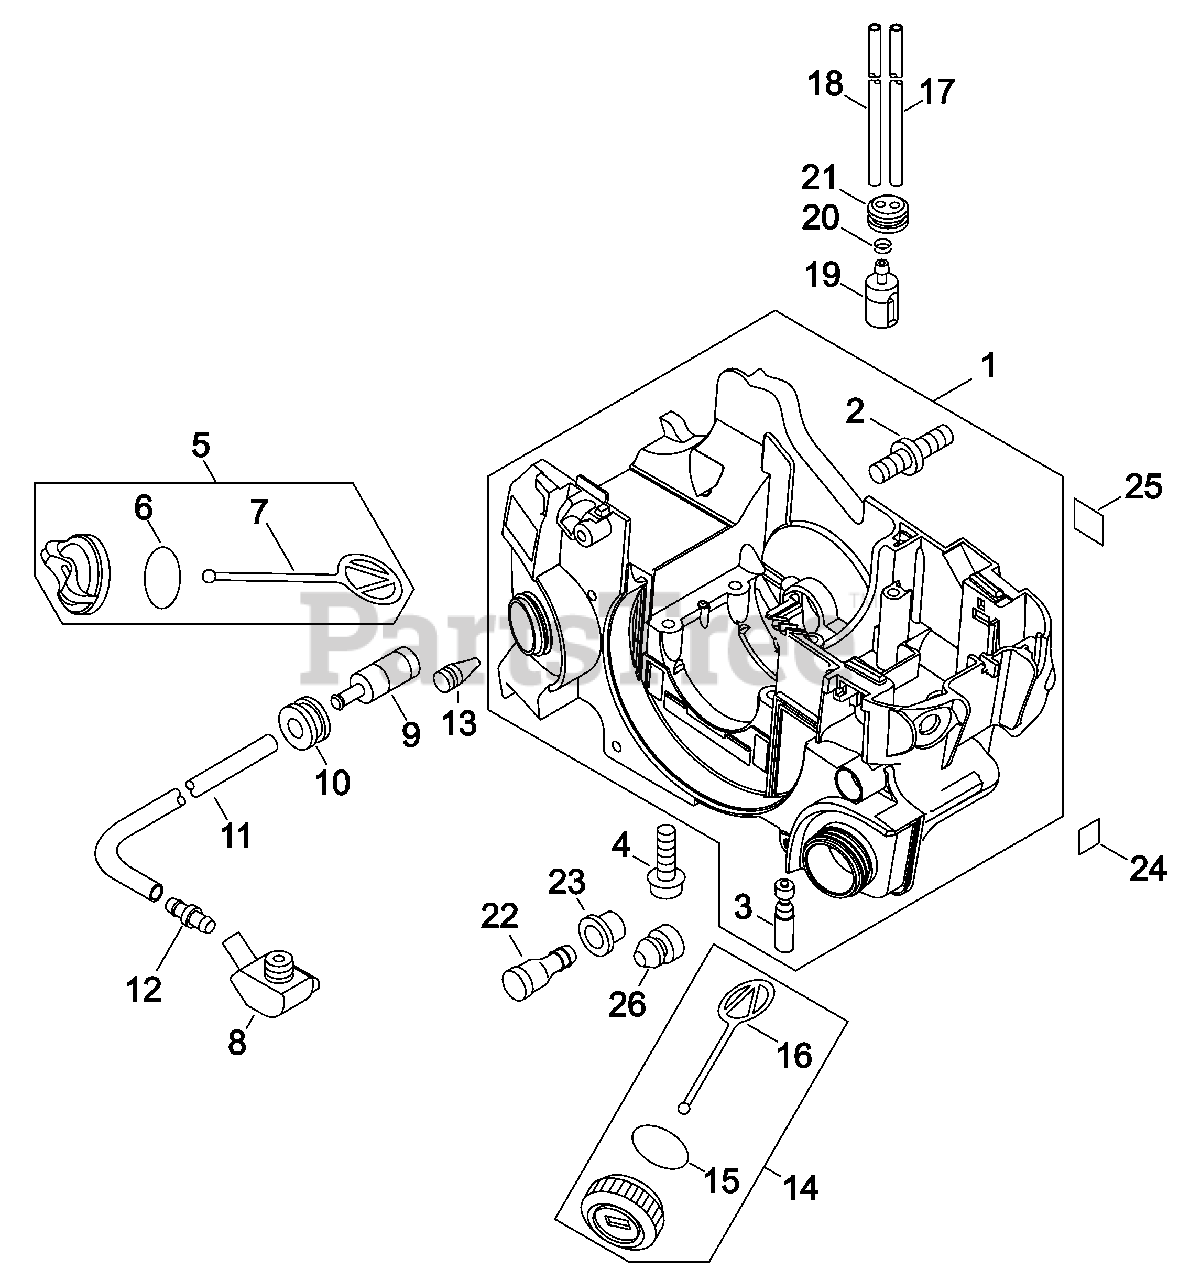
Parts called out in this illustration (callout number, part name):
1	HOUSING ASSY, ENGINE
2	BOLT, STUD 8
3	AUTO-OILER ASSY
4	BOLT, TORX 5×30
5	CAP ASSY - BLACK
6	O-RING 18
7	CONNECTOR, CAP L= 60 MM
8	GROMMET, OIL
9	FILTER, OIL
10	GROMMET
11	PIPE 3×6×185 MM BLACK
12	CONNECTOR, PIPE
13	VENT ASSY
14	CAP ASSY, FUEL
15	O-RING 22
16	CONNECTOR, CAP L= 60 MM
17	PIPE, FUEL 2.4×5×80 BLACK
18	PIPE, FUEL 3×5×230 BLACK
19	FILTER, FUEL
20	CLIP Ø6
21	GROMMET, FUEL
22	VENT ASSY
23	GROMMET, FUEL
24	LABEL, ON-OFF
26	CUSHION
